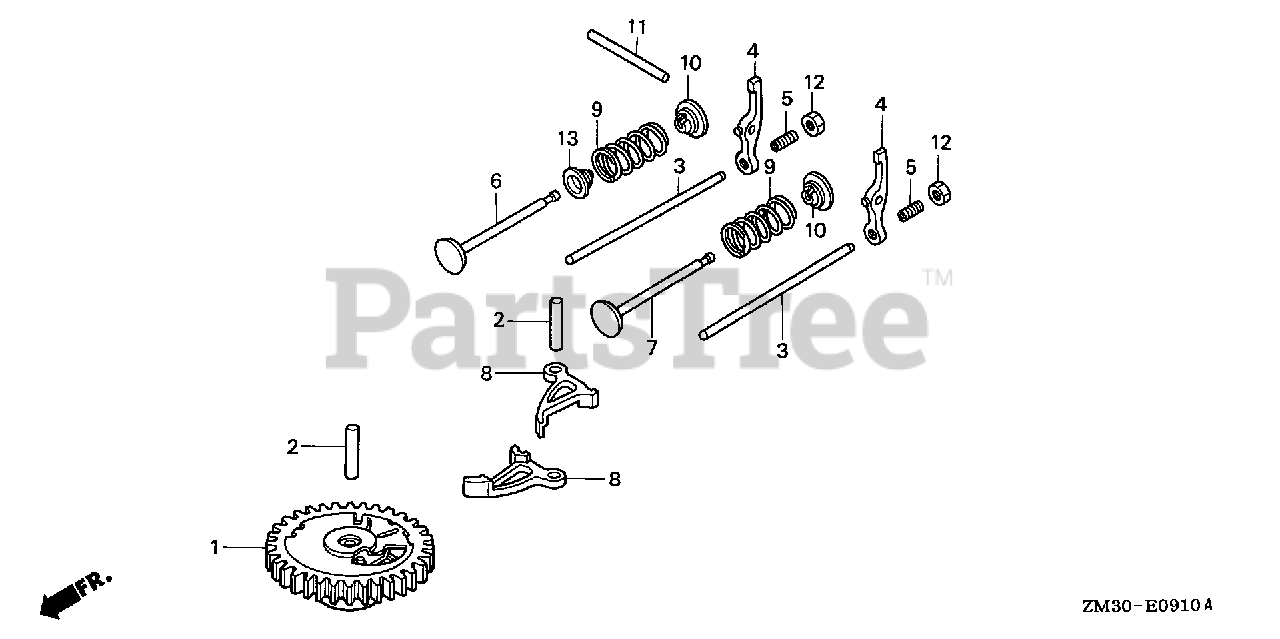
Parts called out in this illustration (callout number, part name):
1	CAMSHAFT ASSY.
2	ROLLER (5X23.8)
4	ARM, VALVE ROCKER
5	PIVOT, ROCKER ARM
6	VALVE, IN.
7	VALVE, EX.
8	LIFTER, VALVE
9	SPRING, VALVE
10	RETAINER, VALVE SPRING
11	ROLLER (4X28)
12	NUT, TAPPET ADJUSTING
13	SEAL, VALVE STEM
